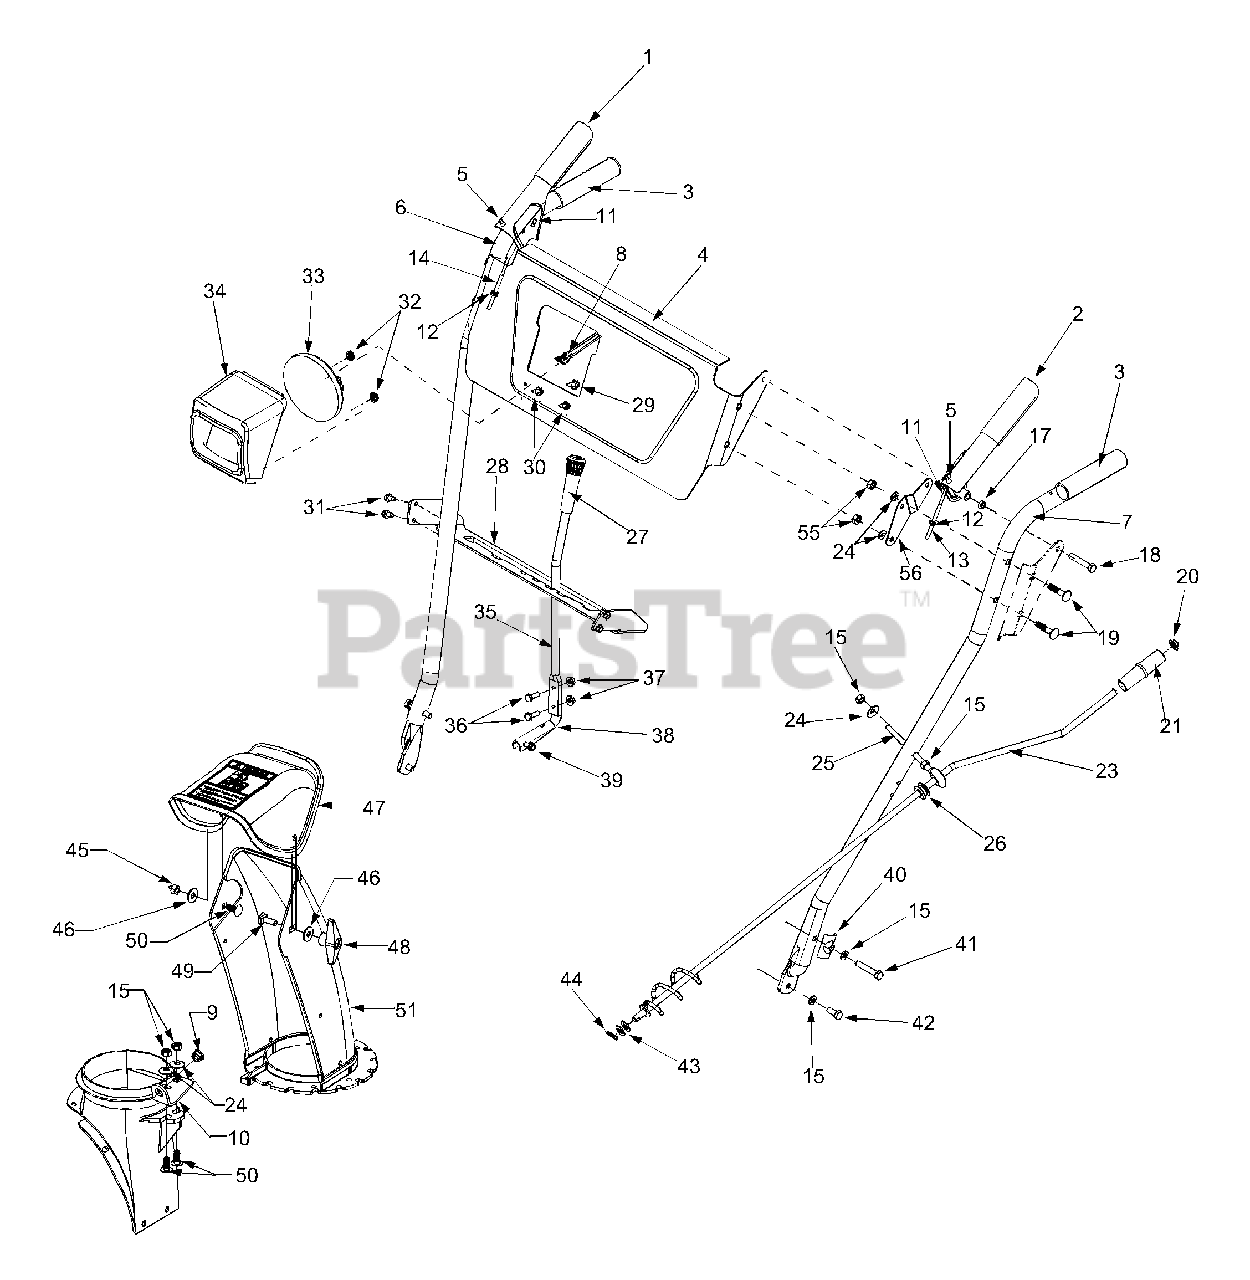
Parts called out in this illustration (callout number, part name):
1	Clutch Lever Assembly - RH
2	Clutch Lever Assembly - LH
5	Bumper Rubber
9	Bushing Plastic .380
11	"Z" Fitting
12	Hex Nut
13	Auger Clutch Cable
14	Drive Clutch Cable
15	Hex Nut 5/16-18
16	Lock Washer 5/16
17	Spacer
18	Hex Hd. Cap Screw 5/16-18 x 2.00
19	Carriage Bolt 5/16-18 x 1.5
20	Push Rod Cap
21	Chute Crank Knob
22	Roll Pin
23	Chute Crank Assembly
24	Bell Washer .340 ID x .873 OD
25	Eyebolt
26	Rubber Grommet
29	Hex Washer Screw 1/4-20 x .625
30	Hex Washer Screw #10 16 x .625
31	Hex Washer Screw 1/4-20 x .50
32	Hex Nut
33	Headlight 18 Watt
34	Headlight Cover
36	Hex Cap Screw 1/4-20 x .75
37	Hex Lock Nut 1/4-20
38	Shift Lever Support
39	Hex Washer
40	Handle Tab
41	Hex Cap Screw 5/16-18 x 2"
42	Hex Cap Screw 5/16-18 x .75
43	Flat Washer 3/8 ID x .738 OD
44	Cotter Pin
45	Hex Lock Nut 5/16-18
46	Washer 5/16
47	Upper Chute
48	Knob 5/16-18
49	Carriage Screw 5/16-18 x 1.0
50	Carriage Bolt 5/16-18 x .75
51	Lower Chute
52	Hex Lock Nut 1/4-20
53	Chute Flange Keeper
54	Hex Cap Screw 1/4-20 x .75
55	Hex. Wash. Locknut 5/16-18 Thd.
